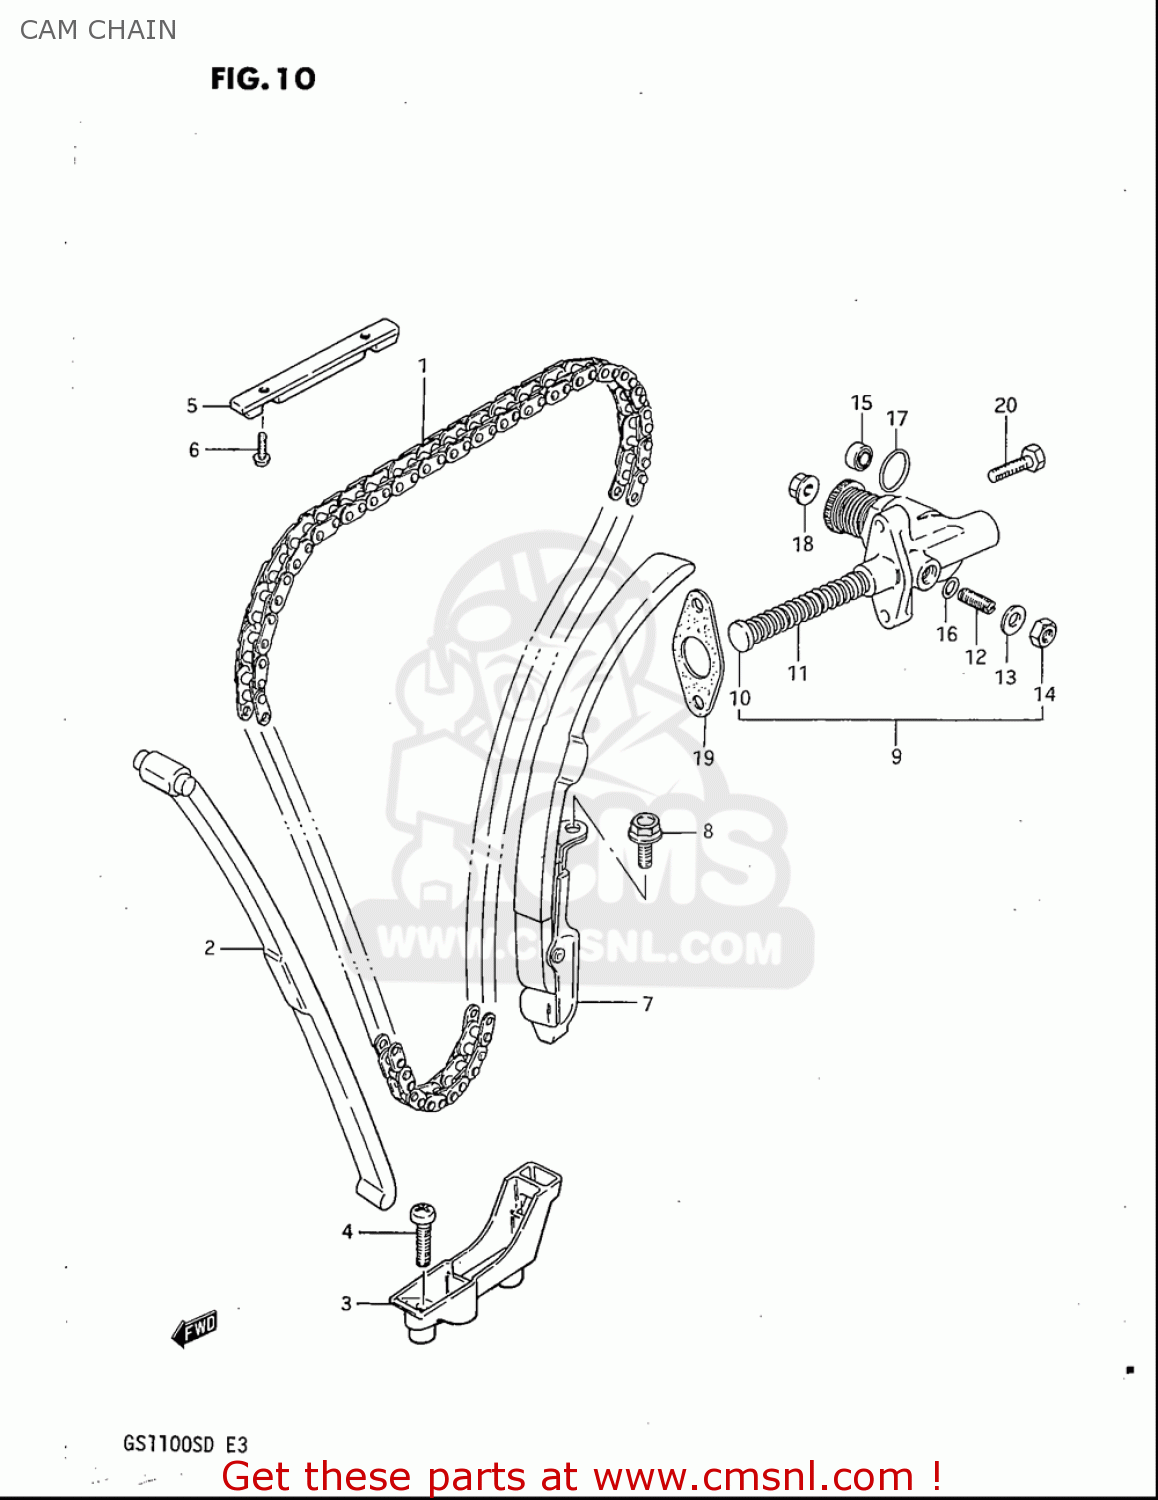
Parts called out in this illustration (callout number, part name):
1	CHAIN,CAMSHAFT DRIVE(120L)
2	GUIDE,CAM CHAIN NO.1
3	HOLDER,CAM CHAIN GUIDE
4	SCREW
5	GUIDE,CAM CHAIN
6	SCREW
7	TENSIONER,CAM CHAIN
8	BOLT
9	ADJUSTER,CAM CHAIN TENSIONER
10	ROD,PUSH
11	SPRING
12	SCREW
13	WASHER
14	NUT
15	SEAL,OIL(10X16X4)
16	O RING(D:1.9,ID:5.7)
17	O RING(D:2.4,ID:20.8)
18	NUT
19	GASKET,TENSIONER ADJUSTER (NAS)
20	SCREW (6X25)
